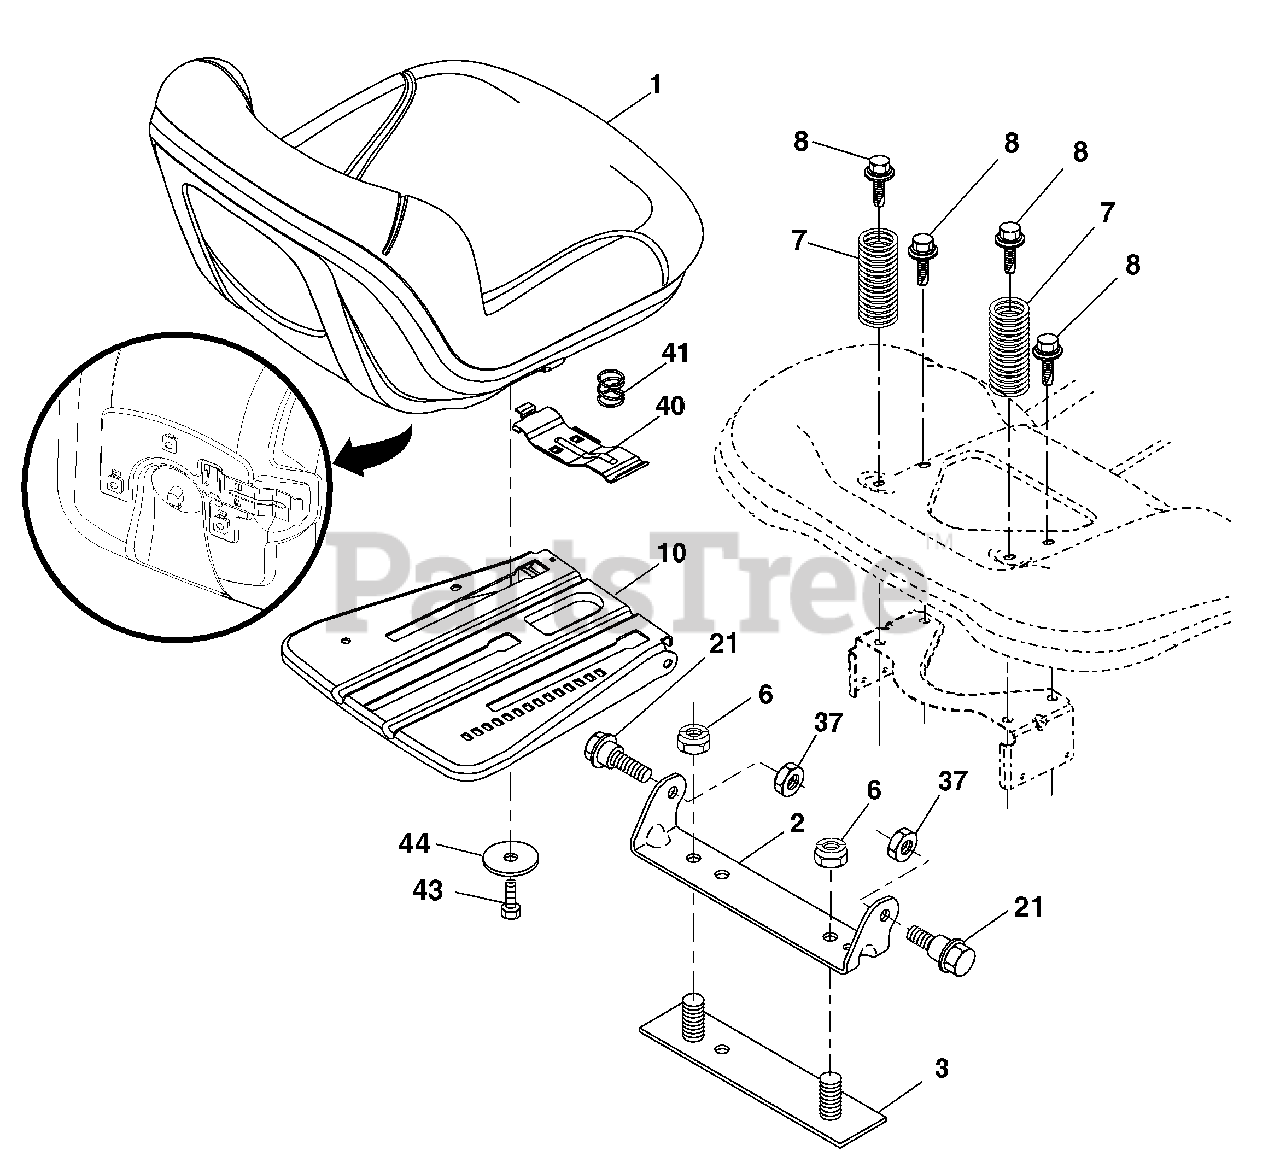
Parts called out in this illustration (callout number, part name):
1	Seat
2	Bracket Pivot Fender
3	Strap, Asm Fender
6	Nut, Lock W/Ins. 3/8-16 unc
7	Spring, Seat Cprsn
8	Bolt 5/16-18 uncx 3/4 w/Sems
10	Pan, Seat
21	Bolt, Shoulder 5/16-18
37	Nut, Lock 5/16-18 unc
40	Handle Slide Seat
41	Spring Latch Seat
43	Bolt Fin Hex 3/8-16 unc x 3/4
44	Washer 13/32 x 2-3/8 x 12 Ga.
